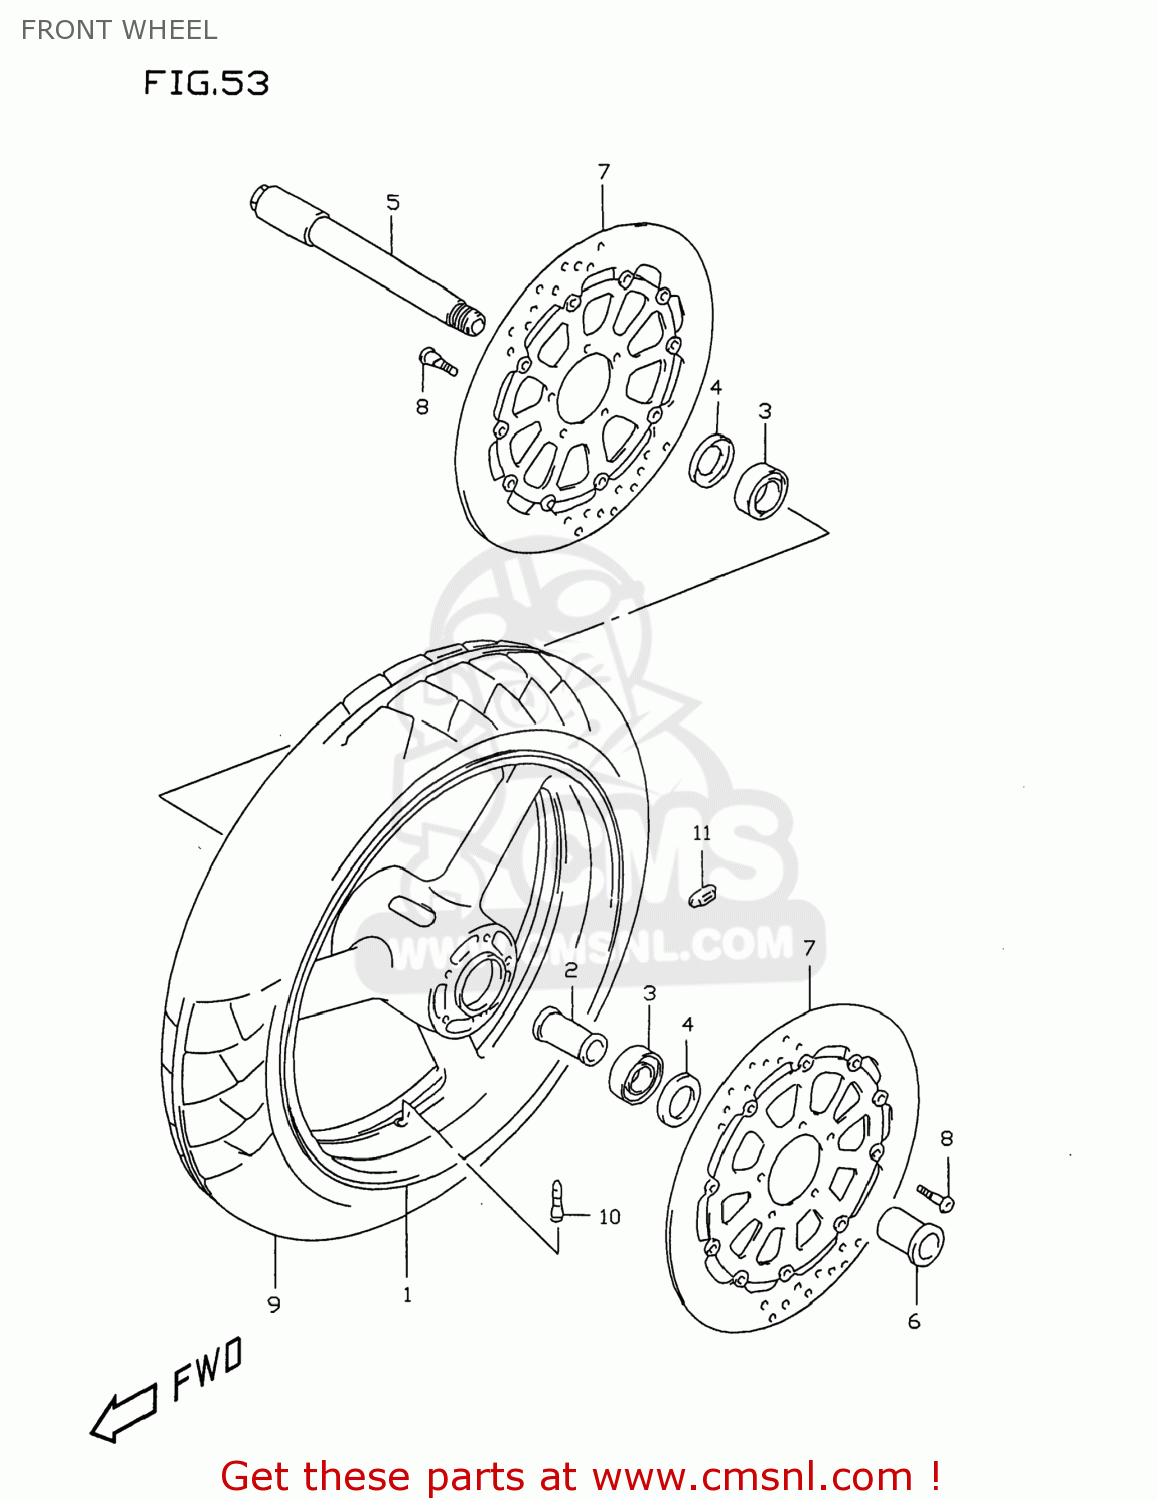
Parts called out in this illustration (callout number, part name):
1	WHEEL,FRONT (17XMT3.50)(
2	SPACER,FR HUB BEARING
3	BEARING(25X52X15)
4	SEAL,OIL(32X52X7)
5	AXLE,FR
6	NUT,FR AXLE
7	DISC,FR BRAKE
8	BOLT 8X33
9	TIRE,FRONT 120/70 ZR17
10	VALVE ASSEMBLY,WHEEL,TR412
11	BALANCER,WHEEL (10G)
